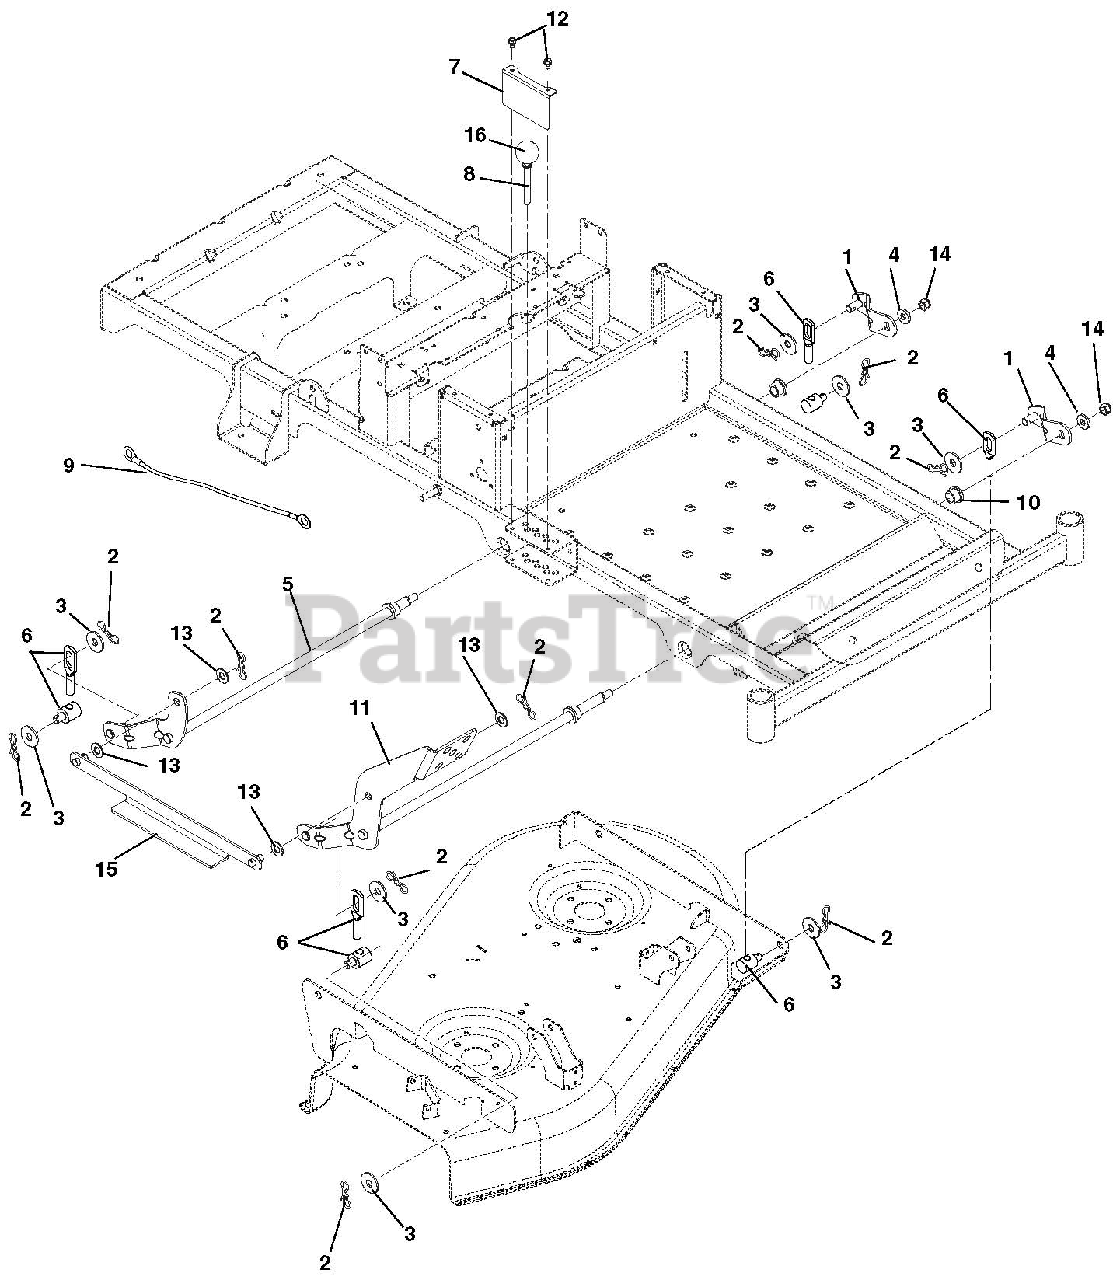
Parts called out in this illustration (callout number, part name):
1	WMT, LIFT ARM
2	PIN,BOW TIE LOCKING .091X1.875
3	WSHR-FL-STL.511X1.441X.125 YWZ
4	WSHR,FLT .438X1.00X.160 ZCC
5	WMT, REAR DECK LIFT SHAFT
6	ASM, DECK LINK
7	GUARD, DECK LIFT
8	PIN, DECK
9	LANYARD, GALV 12"
10	BSHG-FLG .629X.879X.469X1.250
11	WMT, DECK LIFT PEDAL
12	@SCR-TAP .25-20X.37 HWH YWZ TR
13	WSHR-FL-NYL .518X1.000X.080
14	NUT-LK-NYL .44-20 YWZC
15	WMT, LIFT LINK
16	KNOB,BALL -BLACK 1.47" .375-16
